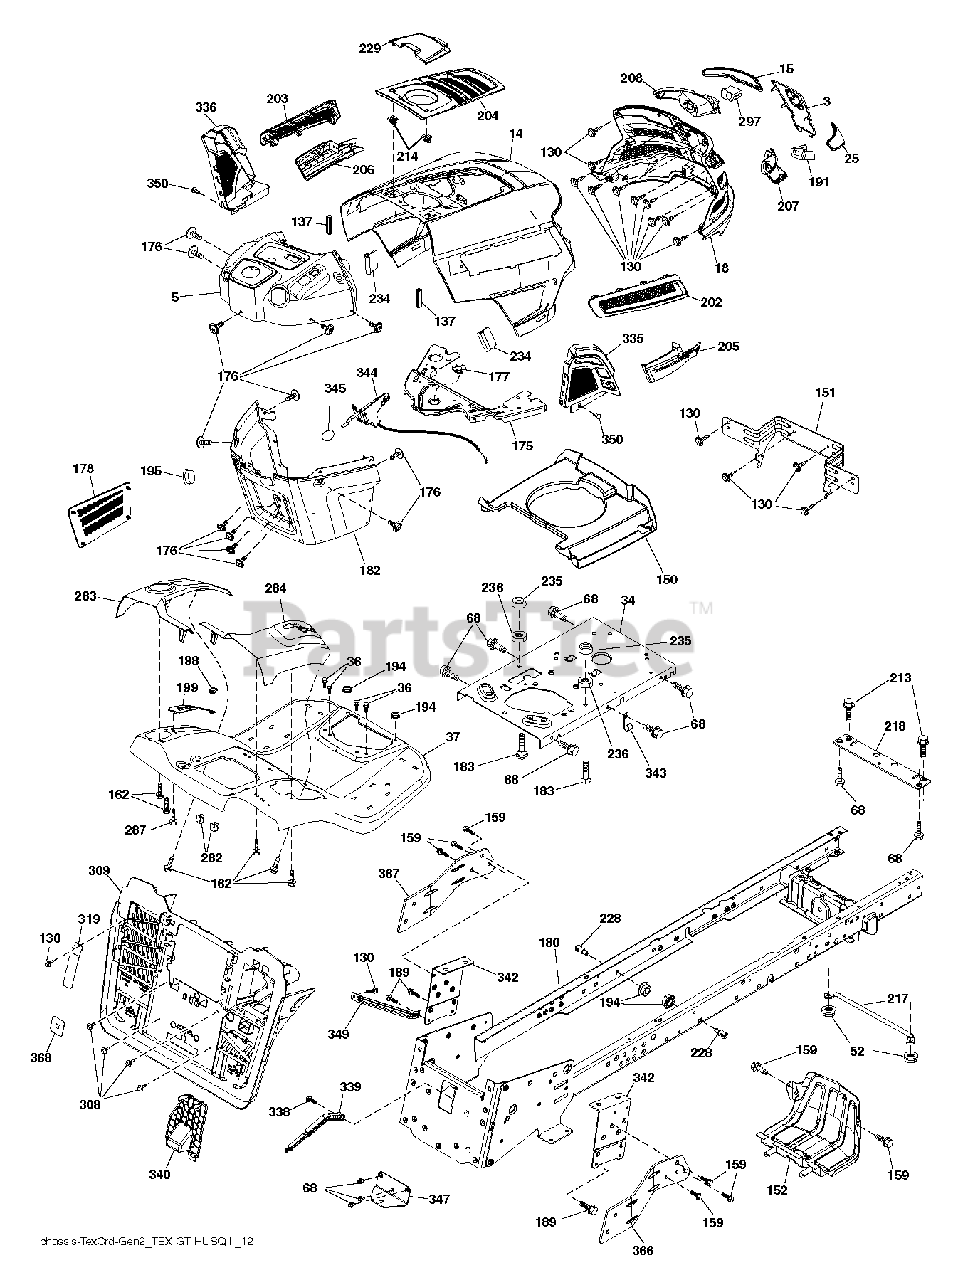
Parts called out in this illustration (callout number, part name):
3	APPLIQUE.SUBASM.GT.HUSQ.II
5	DASH.HUSQ2.SM.E.NC.HR.CHG.498
14	HOOD.ASM.HUSQVARNA.GT.TEX.ORAN
15	LENS.HEADLIGHT.LH.GTII.2011
18	GRILLE.SUBASM.GT.HUSQ.II
25	LENS.HEADLIGHT.RH.GTII.2011
34	PLATE.ENGINE.WELDED.CHASSIS
36	SCREW 5/16"
37	FENDER.TEX.SRD.CRD.BASE
52	LOCKNUT
68	SCREW LT
130	SCREW.#10 X 0.750.BOS
137	BUMPER DASH
150	AIR.DUCT.GTV.BLACK
151	BRACKET.PIVOT.HOOD.GT.HUSQ.II
152	SHIELD.BROWNING.PNT.GT.V2
159	SCREW, 3/8-16X3/4
162	SCREW.HI-LO.CONSOLE
175	PLATE.CROSSMEMBER.HUSQ
176	SCREW.#10-24X5/8.RN.QU
177	BUSHING, STEERING
178	CARGO.ASM.NET.TXGT.W/C
180	WELDMENT.CHASSIS.TEX.CRD.GEN.2
182	DASH DASH LOWER
183	BOLT.5/16-18X1-1/4 FULL THD
189	SCREW
191	INSERT.REFLECTIVE.RH.HUSQ.GTII
194	NUT LOCK HEX FLANGE 5/16-18
195	PLUG.HOLE.DASH.LOWER.12V.BLK
198	INDICATOR.DECK.LIFT.RED
199	PLATE DECK LIFT
202	VENT.SIDE.RH.GT.HUSQ.II.
203	VENT.SIDE.LH.GT.HUSQ.II.498
204	VENT.TOP.EXTERNAL.FILL.GT2.GRE
205	SIDE.TRIM.RH.GT.HUSQ.II
206	SIDE.TRIM.LH.GT.HUSQ.II.GRAY
207	BEZEL LIGHT.RH.GT.II.MYLAR
208	BEZEL LIGHT.LH.GT.II.MYLAR
213	BOLT
214	CLIP.RETAINER.TINNER.
217	ROD.PIVOT.HOOD
218	X-PIECE.HOOD.STOP.NON/
228	STUD.FASTNER.W/ANTI-ROTATE
229	LID.EXT.FILL.GT.HUSQ2.BLACK
234	BUMPER.HOOD.TEX.HUSQVARNA
235	SPACER FENDER
236	NUT.CENTERLOCK.5/16-
282	CLIP.RETAINER.CONSOLE.LT.HUSQ
283	CONSOLE.DECKLIFT.CRDII.498
284	CONSOLE.PEDAL.HYDRO
287	SCREW 1/4X20
297	INSERT.REFLECTIVE.LH.HUSQ.GTII
308	BOLT, 5/16-18 X 1 3/4
309	BACKPLATE.SUBASM.SERV.TEX.CRD.
335	COVER.LOWER.DASH.RH.BLACK
336	COVER-LH.LOWER.DASH.GT2.BLACK
338	BOLT BOLT SHOULDER
339	LEVER LEVER BAGGER
340	BATTERY.DOOR.TEX.CRD.GEN.2,1
342	SUPPORT SUPPORT FENDER
343	CLIP CLIP
344	CONTROL.EZ.MULCH.TEX/CRD
345	RP KNOB.OVAL.TAPERED.3/8-16BLK
347	HITCH TOW
349	BRACKET.SUPPORT.LRVB/CRD
350	CLIP.X-MAS.TREE
366	BRACKET.RH.FRONT.BAGGER.BLACK
367	BRACKET.LH.FRONT.BAGGER.BLACK
368	FULL.LEVER.BAGGER.TEX.CRD
